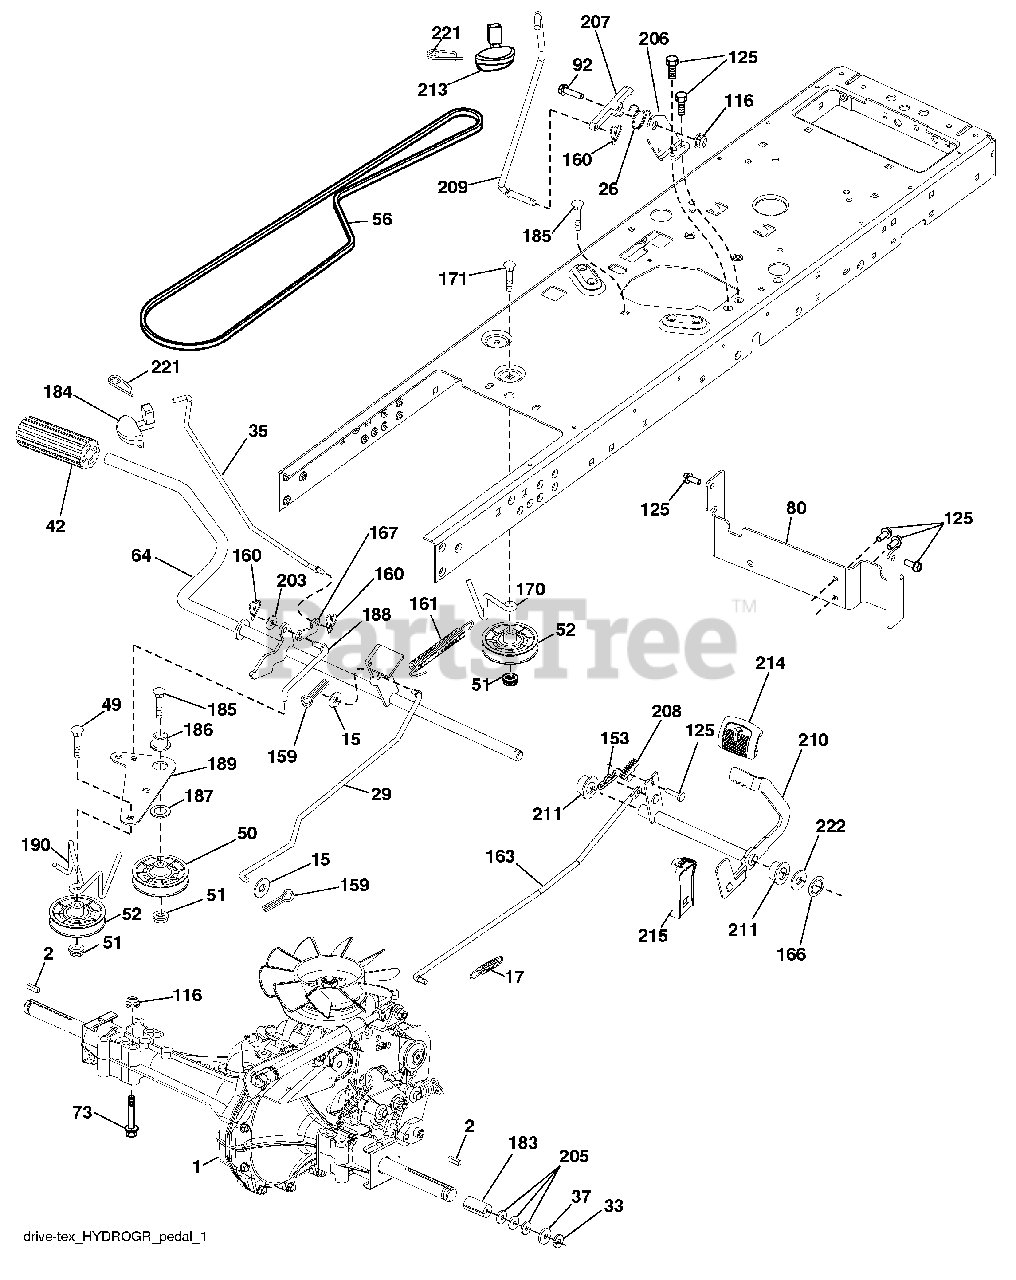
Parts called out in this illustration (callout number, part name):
2	Key
15	Washer 13/32 x 13/16 x 16 Ga.
17	Spring, Brake
26	Spring Return Cruise
29	Rod, Brake
33	Ring E
35	Rod, Brake, Park
37	Washer 25/32 x 1-1/4 x 16 Ga.
42	Cover, Foot Pedal
49	Bolt
50	Pulley Idler Flat
51	Lock Nut 3/8-16
52	Idler V-Groove 910" Offset
56	V-Belt, Drive
64	Shaft Asm. Pedal Brake Control
73	Bolt Hex 5/16-18 x 3.75
80	Bracket Strap Torque
92	Bolt Fin Hex 5/16-18 unc x 1.25
116	Nut Lock Hex Flange 5/16-18
125	Screw 5/16-18 x 3/4
153	Retainer Spring
159	Pin Cotter 1/8 x 3/4
160	Retainer Clip
161	Spring, Return, Clutch
163	Rod Pedal Control
166	Nut Push .625
167	Latch Brake Parking
170	Keeper Belt Centerspan
171	Bolt
183	Spacer Axle
184	Handle Parking Brake
185	Bolt
186	Spacer Retainer
187	Washer
188	Link Clutch Ground Drive
189	Bellcrank Ground Drive
190	Keeper Bellcrank Ground Drive
203	Washer 11/32 x 11/16 x 16 Ga.
205	Washer 25/32 x 1-5/8 x 16 Ga.
206	Bracket Mount Latch Cruise
207	Latch Control Cruise
208	Gear Sector Control Cruise
209	Rod Control Cruise
210	Rockr Asm. Pdeal Control
211	Bearing Nylon
213	Knob control Cruise
214	Pad Pedal Forward
215	Pad Pedal Reverse
221	Retainer Spring Clip Handle
222	Washer 21/32 x 1-1/4 10 Ga.
